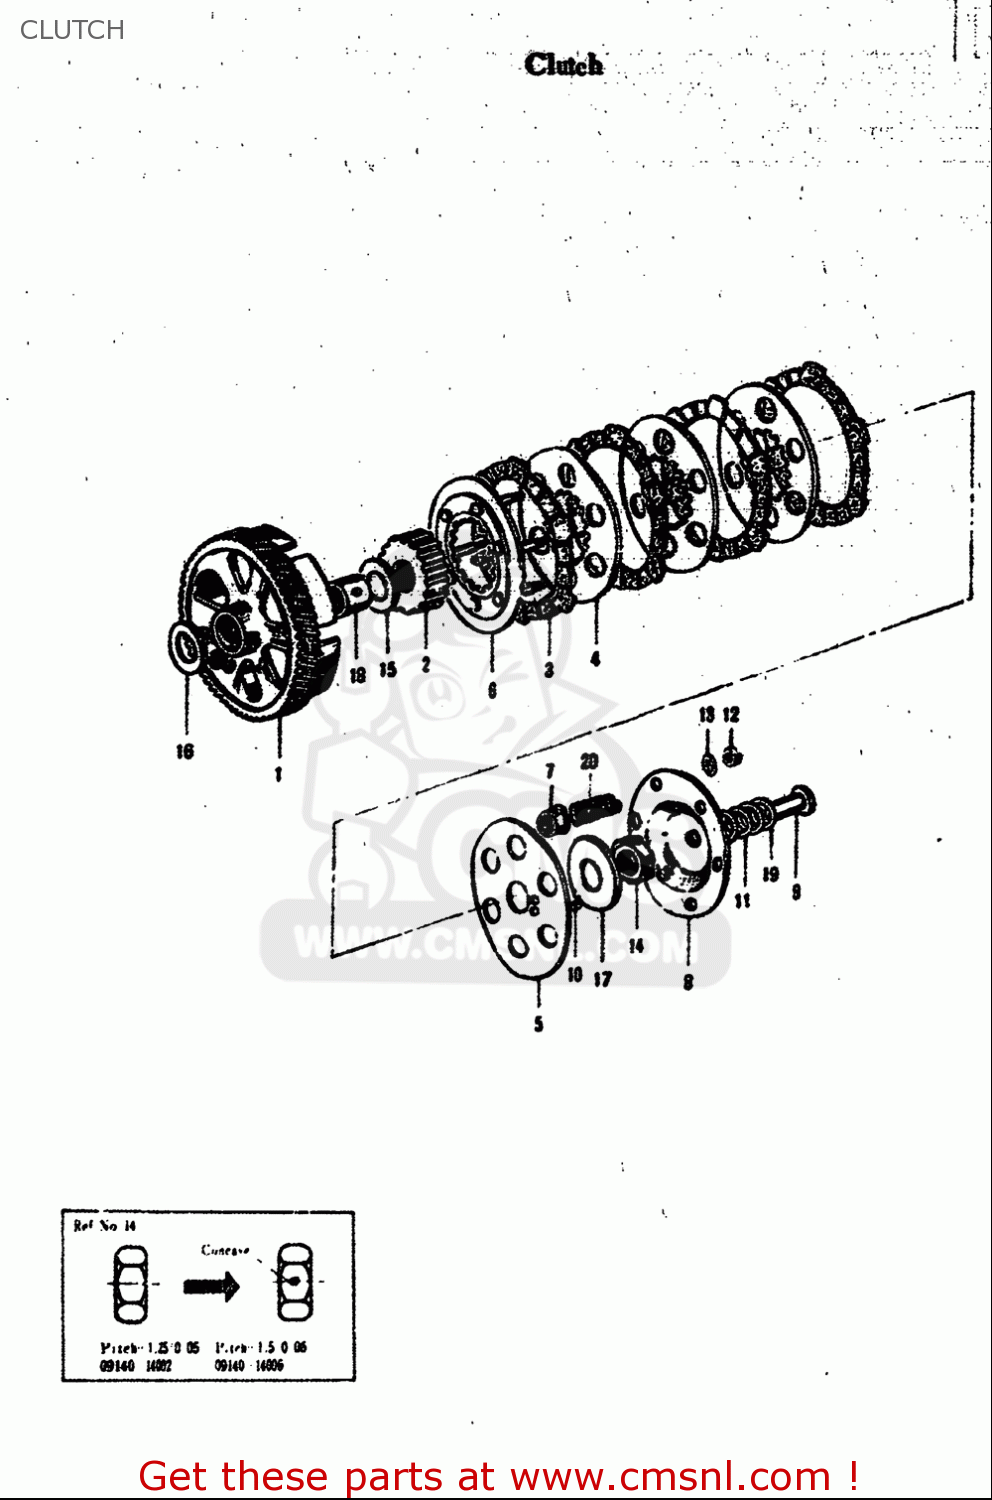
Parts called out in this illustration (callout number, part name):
10	PIN
11	WASHER
12	NUT
14	NUT
15	SHIM(17X30X1)
16	WASHER
20	CLUTCH SPRING
